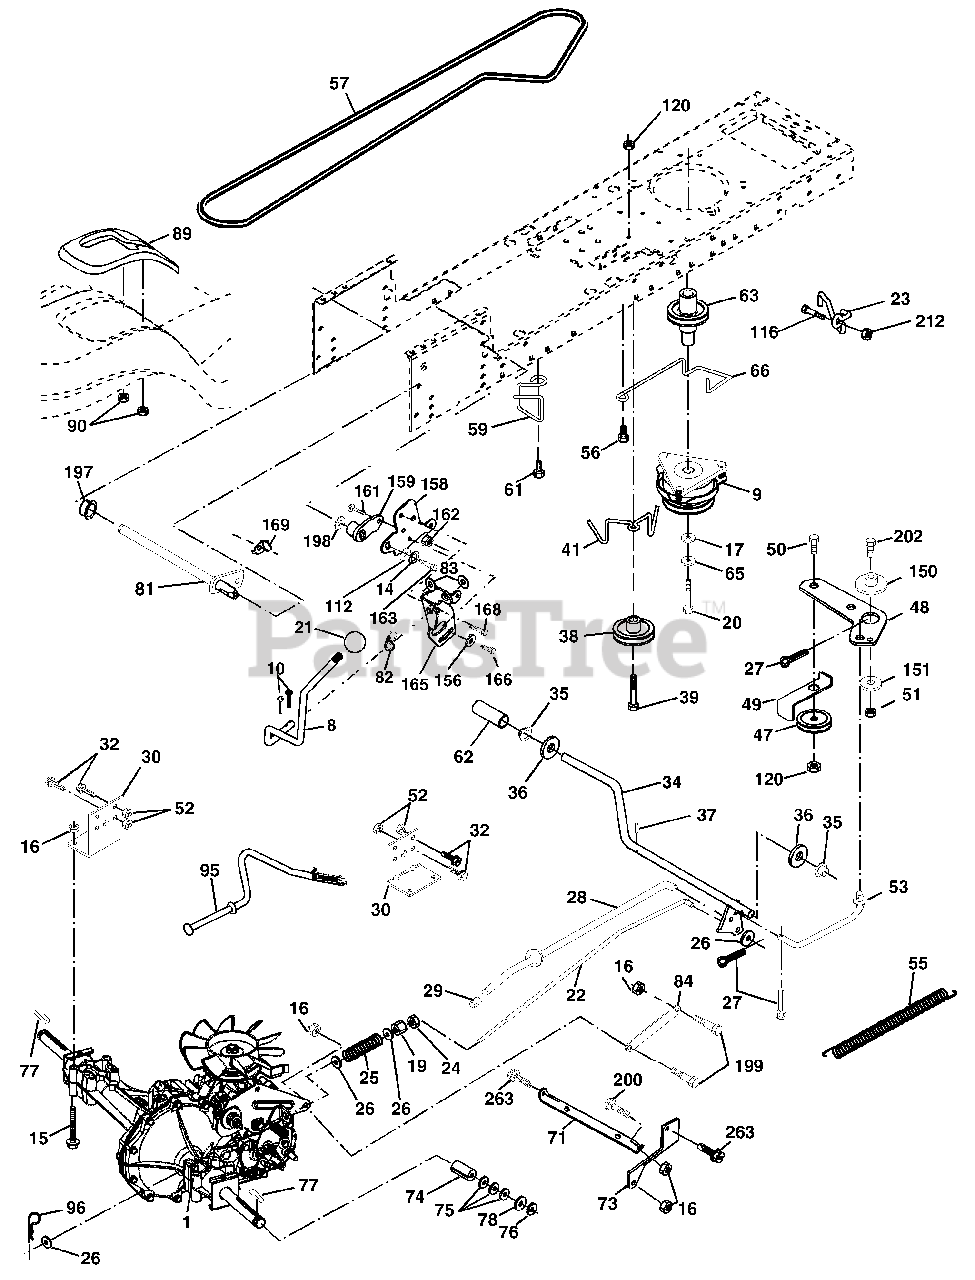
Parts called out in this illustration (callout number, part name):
8	Rod Shift Fender
9	Clutch Electric
10	Pin Cotter 1/8 x 1 CAD
14	Washer Lock Hvy Helical
15	Bolt Hex Flghd 5/16-18 Gr. 5
16	Nut Lock Hex W/Ins. 5/16-18 unc
17	Washer 1-1/2 OD x 15/32 ID x .250
19	Nut Lock Hex W/Wsh 3/8-16 unc
20	Bolt, Hex 7/16-20 x Gr. 5-1.5
22	Rod, Brake Hydro
23	Bracket Asm. Anti-Rot CVX
24	Locknut
25	Spring, Brake Rod
26	Washer
27	Pin Cotter 1/8 x 3/4 CAD.
28	Rod, Parking Brake
29	Cap, Parking Brake
30	Bracket, Transaxle
32	Bolt Hex Hd 5/16-18 unc x 3/4
34	Shaft, Foot Pedal Nibbed
35	Bearing, Nylon
37	Pin, Roll
38	Pulley, Idler, Flat Composite
39	Bolt 3/8-16 x 2-3/4 Gr. 5
41	Keeper, Belt Idler Fool-Proof
47	Pulley, Idler, V-Groove
48	Bellcrank Clutch Grnd Drv Stl
49	Retainer, Belt
50	Bolt Carr. SH 3/8-16 x 1-1/2 Gr. 5
52	Nut Crown Lock 5/16-18
53	Link, Clutch
55	Spring, Return, Clutch
56	Screw 3/8-16 x 1-1/4
57	V-Belt, Ground Drive
59	Keeper, Center Span
61	Screw 3/8-16 x .875
62	Cover, Pedal
63	Pulley, Engine
65	Washer
66	Keeper Belt Engine Hydro
71	Strap Torque Lh Hydro
73	Strap Torque Rh Hydro
74	Spacer, Axle
75	Washer 25/32 x 1-1/4 x 16 Ga.
77	Key, Square
78	Washer 25/32 x 1-5/8 x 16 Ga.
81	Shaft Asm. Cross Hydro
82	Spring Torsion T/A
83	Washer 17/32 x 3/4 x 16 Ga.
84	Link Transaxle
89	Console, Shift
90	Nut, Self Thd Wsh Hd 1/4 Zinc
95	Control Asm. Bypass Hydro
96	Retainer Spring 1" Zinc/Cad
112	Washer 9/32 x 3/4 x 10 Ga.
116	Bolt RDHD SQNK 3/8-16 unc x 1
120	Nut Lock 3/8-16
150	Spacer Retainer
151	Washer 13/32 x 2 x 10 Ga.
156	Washer Srrted 5/16 ID x 1.125
158	Bracket Shift Mount
159	Hub Shift
161	Bolt Rdhd Sqnk 1/4-20 x 3/4 Gr. 5
162	Nut Crownlock 1/4-20 unc
163	Bolt Hex Fin 1/4-20 unc x 1 Gr. 5
165	Bracket Pivot Lever
166	Screw 5/16-18 x 5/8
168	Bolt Shoulder 5/16-18 x .561
169	Plate Fastening Lt\
197	Nyliner Snap-In 5/8" ID
198	Washer Nyliner 7/8 ID x .105
199	Bolt Shoulder 5/16-18 unc
200	Bolt Rdhd Sq Neck 5/16-18 unc x 1
202	Bolt 3/8-16 x 1-3/4 Gr. 5
212	Nut Hexflange Lock
263	Screw Hexwsh Thdr 3/8-16 x 3/4
